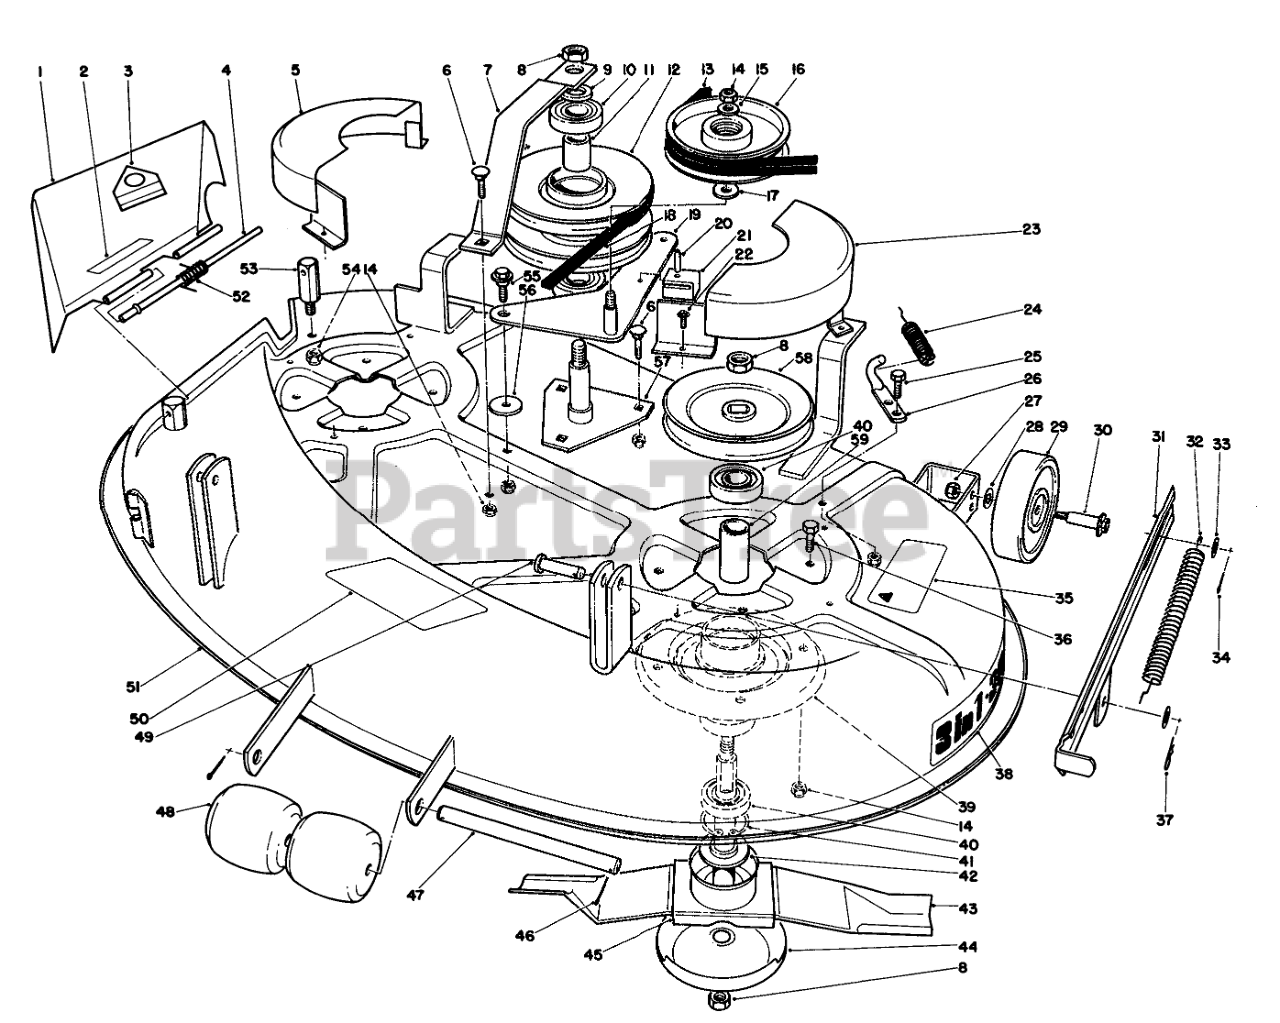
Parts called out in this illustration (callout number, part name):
1	Deflector Assembly (Incl. Ref. #2-3)
2	DECAL-NO STEP
3	DECAL-DANGER
4	ROD-HINGE DEFLECTOR
5	RH BELT COVER WA B
6	BOLT-CARR
7	Support-Pulley
8	NUT-LOCK NI
9	WASHER-FLAT
10	BEARING-BALL
11	TUBULAR SPACER
12	Pulley Assembly (Incl. Ref. #10-11)
13	V-BELT
14	NUT-LOCK, NI
15	WASHER-FLAT
16	PULLEY-IDLER
17	WASHER-FLAT
18	V-BELT
19	Bracket-Idler
20	PIN-COIL
21	IDLER BRKT GUIDE
22	SCREW-HWHTF
23	Cover-Belt L.H.
24	DECK TENSION SPRNG O
25	SCREW-HH
26	SPRING ROD
27	NUT-LOCK, NI
28	WASHER-FLAT
29	DECK WHEEL
30	BOLT-WHEEL
31	Strap-Deck Spring (L.H.)
32	DECK TENSION SPRNG O
33	WASHER-FLAT
34	Cotter Pin
35	DECAL-CAUTION, BLADE
36	SCREW-HH
37	PIN-COTTER
38	DECK DECAL
39	Spindle Tube
40	BEARING-BALL
41	RING-RETAINING
42	SPACER-SPINDLE
43	Blade
44	Cup
45	SPINDLE SHAFT WA
46	PIN-COTTER
47	ROLLER SHAFT
48	ROLLER
49	PIN-CLEVIS
50	BELT RTG DECAL
51	DECK WA
52	SPRING
53	REAR PIVOT POST (PLTD)
54	NUT-LOCK, NI
55	SCREW-SHOULDER
56	WASHER-PIVOT
57	Jackshaft
58	Pulley-Spindle
59	BEARING SPACER
